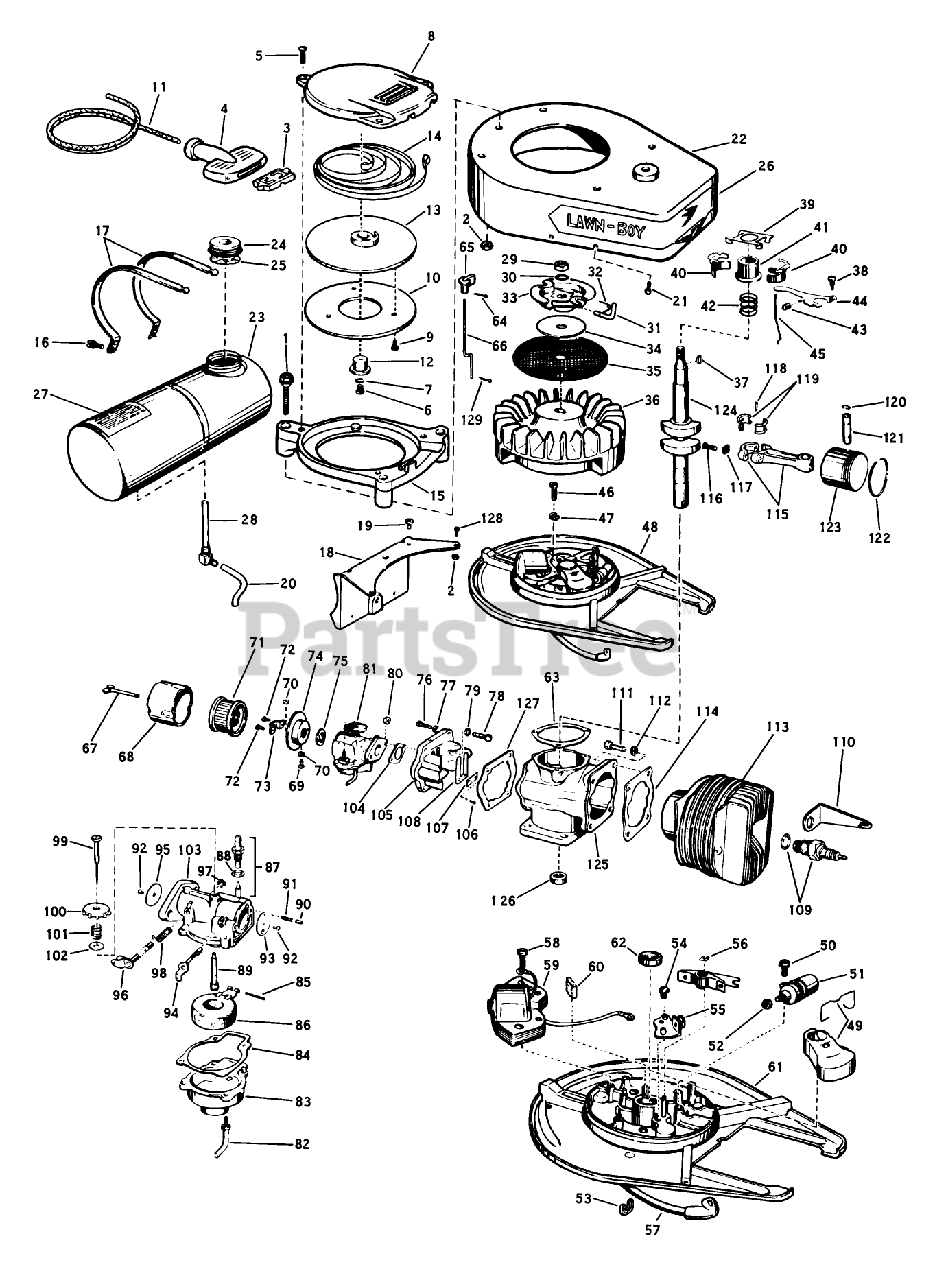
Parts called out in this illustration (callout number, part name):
10	Plate-Pulley
14	RECOIL SPRING
21	SCREW S
24	Gas Cap
26	Decal-"Lawn-Boy"
28	VALVE&SCREEN SM
31	PIN - STARTER
41	COLLAR S
43	WEAR BLOCK S
44	GOVERNER LEVER AY
45	GOVERNOR ROD S
55	BREAKER AY. S
63	GASKET S
64	Cotter Pin-Choke Knob
65	KNOB, CHOKE BAR
76	SCREW S
80	STOP NUT
92	Screw-Choke Disc
98	SPRING
99	NEEDLE AY. S
101	Spring-Ndl. Adj.
104	GASKET S
107	PLATE-BACKUP, REED
109	Spark Plug
114	GASKET S
119	LINER ASM
124	Crankshaft
125	Crankcase Oil Seal Assembly
129	Cotter Pin
